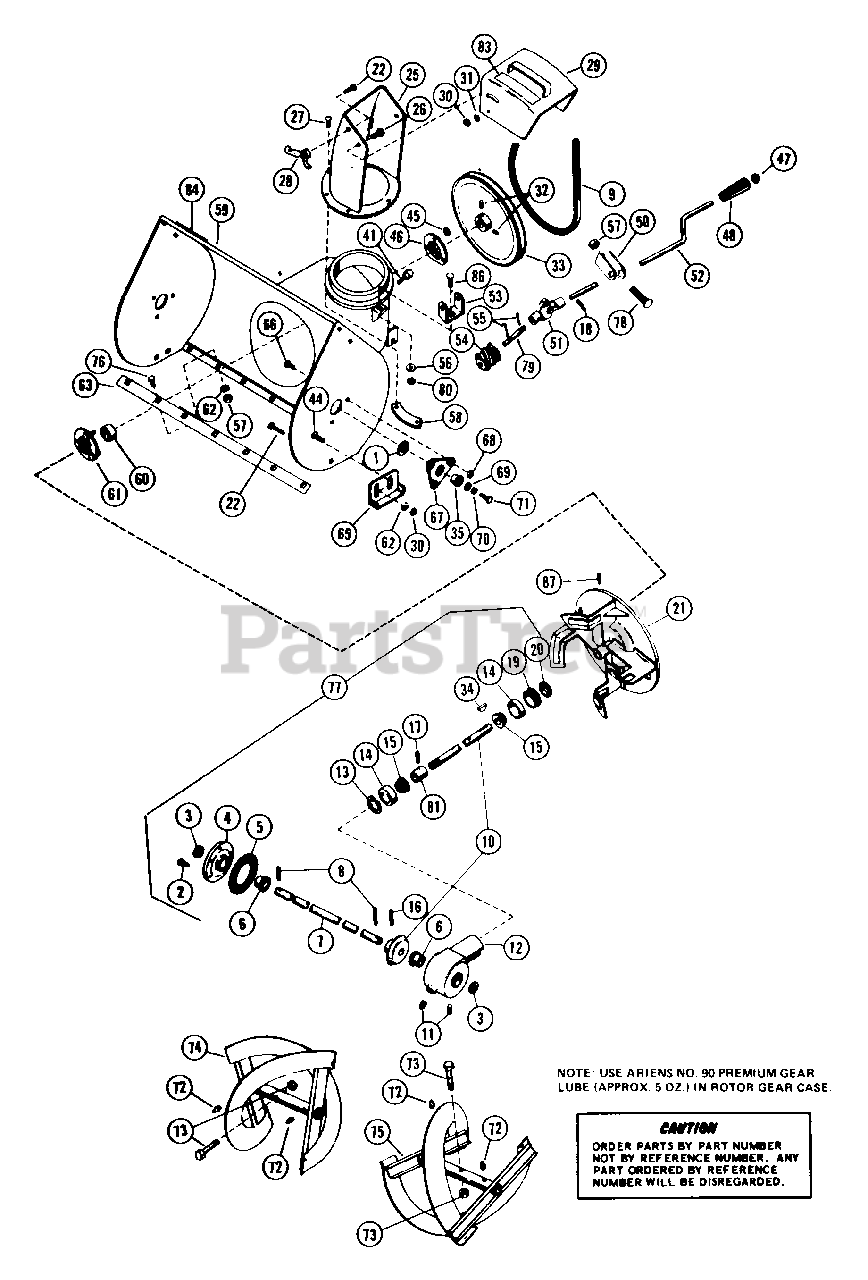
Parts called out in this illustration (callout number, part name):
1	WSHR-FL-STL 1.010X1.505X.062PL
2	BLT-SERHFWH .25-20X.75 PL
3	SEAL 1.000X1.312X.150
4	GEAR CASE FLANGE
6	BSHG-FLG 1.000X1.12X.62X1.50BR
7	FRONT GEAR SHAFT
8	PIN-ROLL .188X1.50
10	PINION & SHAFT SERVICE ASSEMBL
11	PIPE PLUG
12	CASE, GEAR - C.I.
13	RG-RTNG INT 1.781 HSG X.062
14	BRG-CUP 1.781X.475
15	BRG-CONE .750X.61
16	PIN-ROLL .313X1.38
17	PIN-ROLL .250X1.75
18	PIN-HAIR INT .09X.62X2.25
19	ADJUSTMENT PLUG
20	SEAL .750X1.499X.225
21	FAN - 12"
22	BLT-RDHDSQNK .38-16X.75 SHT PL
25	DISCHARGE CHUTE
26	BLT-HEX .38-16X.75 PL GR2
27	SCR-TAP 10-24X.375 CRPH 1A
28	WING NUT
29	SERVICE DEFLECTOR ASSM
30	NUT-LK-CTR .375-16 GR A PL
31	WSHR-LK .375X.115 HVY PL
32	SCR-SET .32-18X.38 SKHCUPNL OH
33	PLY-? 9.0X.75
34	KEY-WDRF .188X.875X.375 SAE11
35	BSHG-FLG 1.000X1.12X.62X1.50BR
44	BLT-RDHDSQSHNK .38-16X1.00 PL
45	NUT-LK-CTR .250-20 PL
46	BEARING FLANGE
47	CAP, 3/8 ROD YWZC
50	BRACKET
51	UNIVERSAL JOINT ASSEMBLY
52	CHUTE CONTROL CRANK
53	WORM CLEVIS
54	WORM GEAR
55	PIN-ROLL .125X.75
56	WSHR-LK .313X.062
57	NUT-LK .312-18 GR A PL
58	CHUTE CLAMP
59	BLOWER HOUSING 24 IN
60	BRG-BALL .750X1.750X.50
61	BEARING FLANGE
62	WSHR-FL-STL .38X.875X.083 PL
63	SCRAPER BLADE 24"
65	RUNNER
66	SCR-SLTR-SERNK .25-20X.62 PL
67	BEARING SUPPORT
68	NUT-LK-FLG .250-20 PL
69	WSHR-FL-STL .511X1.441X.125 PL
70	WSHR-LK .500X.151 HVY PL
71	BLT-HEX .50-13X1.00 PL GR2
72	SPIN DRIVE ZERK FITTING
73	SHEAR BOLT SERVICE ASSEMBLY
74	RAKE, RIGHT-24"(1ID X 15.88OD)
75	RAKE, LEFT-24"(1"ID X 15.88OD)
76	BLT-RDHDSQNK .312-18X.62 PL
77	GEAR CASE - CAST IRON
78	BLT-RDHDSQNK .31-18X1.75 SHTPL
79	WORM SHAFT
80	NUT-HEX .312-18
81	BEARING SPACER
83	CAUTION LABEL
84	ARIENS NAME PLATE
86	BLT-RDHDSQNK .31-18X.75 GR5 PL
87	PIN-ROLL .250X1.75
